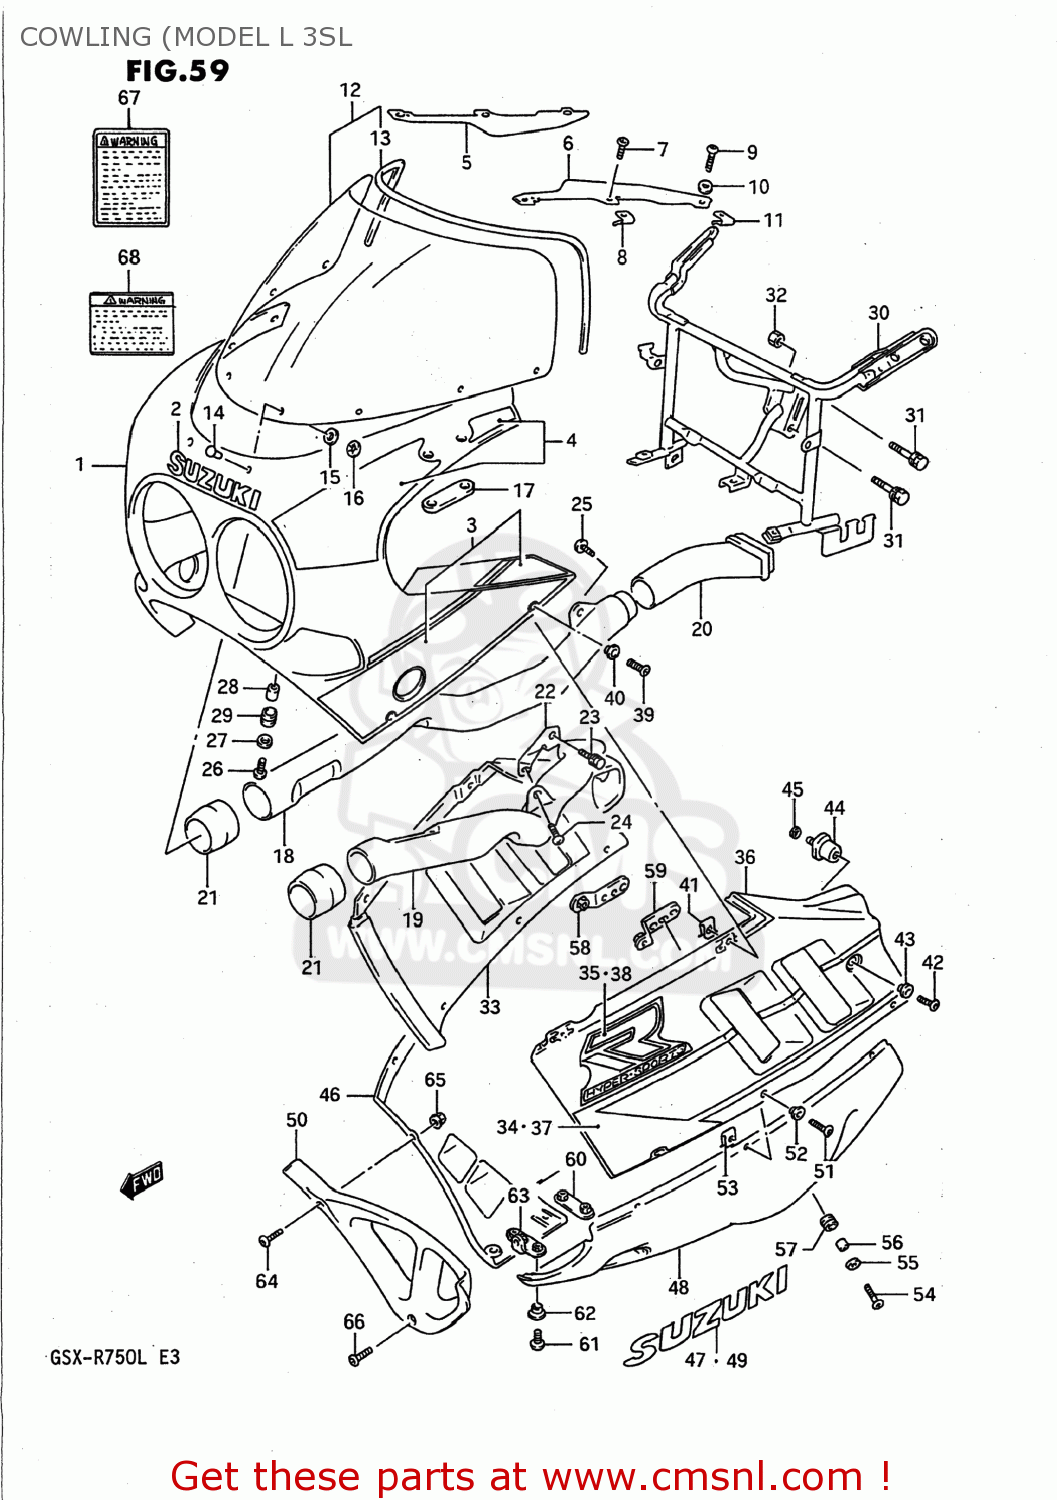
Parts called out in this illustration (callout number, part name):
1	BODY ASSEMBLY,COWLING
2	EMBLEM,FR
3	TAPE SET,COWLING,UPPER
4	TAPE SET
5	PANEL,COWLING UPR,R
6	PANEL,COWLING UPR,L
7	SCREW(5X10)
8	NUT
9	SCREW(5X14)
10	WASHER(5.2X11X1)
11	NUT
12	WINDSCREEN
13	MOLDING,WINDSCREEN
14	PIN,WINDSCREEN
15	CUSHION
16	NUT
17	CUSHION,RR VIEW MIRRORR
18	PIPE,AIR INTAKE,FRONT
19	PIPE,AIR INTAKE,FRONT
20	PIPE,AIR INTAKE RR,R
21	JOINT,AIR INTAKE
22	PLATE,AIR INTAKE,LEFT
23	BOLT
24	SCREW 6X12
25	SCREW
26	SCREW(6X20)
27	WASHER(6.5X18X1)
28	SPACER
29	CUSHION
30	BRACE,COWLING
31	BOLT
32	NUT ,8MM
33	COVER,COWLING SIDE,RIGHT
34	TAPE SET,COWLING SIDE
35	EMBLEM,COWLING SIDE
36	COVER,COWLING SIDE,LEFT
37	TAPE SET,COWLING SIDE
38	EMBLEM,COWLING SIDE
39	SCREW(5X18)
40	WASHER(5.2X14X1.5)
41	NUT,HEADLAMP HOUSING,UPPER
42	SCREW(6X12)
43	WASHER(6.3X16X1.5)
44	CUSHION,COWLING
45	WASHER,LOCK
46	COWLING,UNDER,RIGHT
47	EMBLEM
48	COWLING COMP,UNDER,LEFT
49	EMBLEM,COWLING UNDER,L
50	COWLING,UNDER,CENTER
51	SCREW(5X18)
52	WASHER(5.2X14X1.5)
53	NUT,HEADLAMP HOUSING,UPPER
54	SCREW(6X20)
55	WASHER(6.5X18X1)
56	SPACER
57	CUSHION
58	BRACKET
59	BRACE,COWLING UNDER,LH
60	BRACE,COWLING LWR COVER RR
61	SCREW(6X16)
62	WASHER(6.3X16X1.5)
63	BRACE,COWLING LWR COVER
64	SCREW(5X14)
65	NUT
66	SCREW(6X16)
67	LABEL (WARNING SCREEN)
68	LABEL
